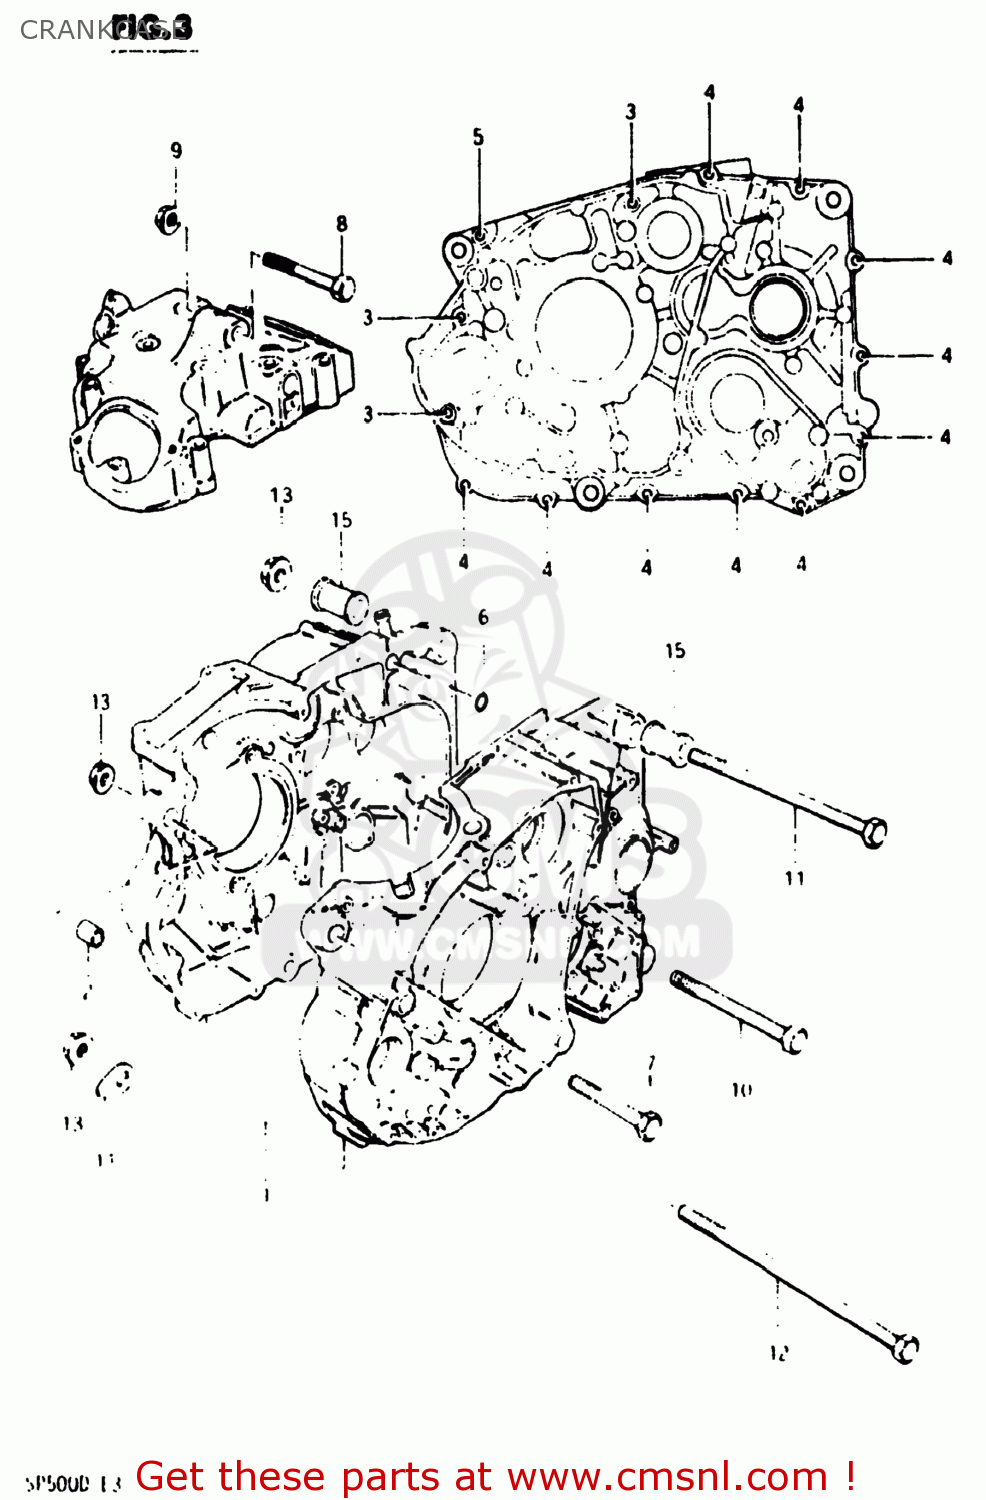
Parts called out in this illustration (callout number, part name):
1	CRANKCASE ASSEMBLY
2	PIN
3	BOLT (6X60)
4	BOLT (6X40)
5	BOLT (6*30)
6	O-RING
7	BOLT 10X70
8	BOLT (8X50)
9	NUT
10	BOLT(10X120)
11	BOLT(10X180)
12	BOLT
13	NUT 10MM
14	WASHER
15	SPACER,ENGINE MOUNT
